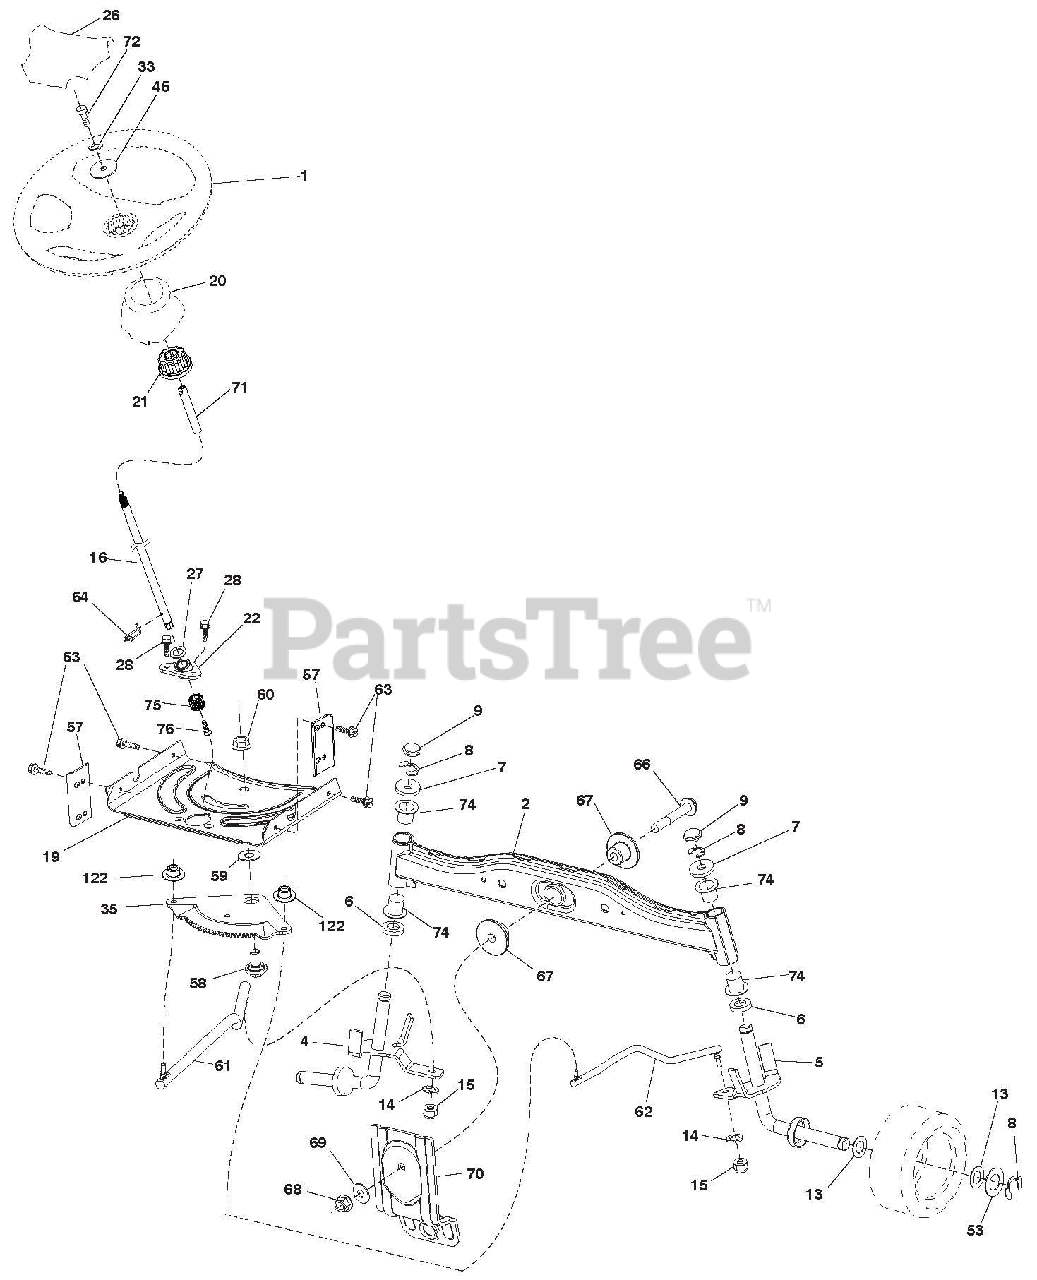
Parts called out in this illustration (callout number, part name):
1	WHEEL.STEERING.HARD RIM.BLACK
2	AXLE HALF.WELDED.
4	SPINDLE.WELDED.LH.15"TEX
5	SPINDLE.WELDED.RH.15"TEX
6	WAHSER THRUST .75 X 1.230
7	WASHER.25/32 X 1-5/8 X 16GA.
8	RING.KLIP.#T5304-75
9	CAP.SPINDLE.FR.TOP.BLK.
13	WASHER.25/32 X 1 1/4 X 16 GA.
14	Washer, Lock 3/8
15	NUT.CROWNLOCK.3/8-24
16	STEERING SHAFT
19	PLATE.STEER.DDL.NLT/NGT
20	BOOT.STEERING.LT.TEX P/L.428
21	ADAPTER.WHEEL.STRG..760
22	STEER.SUPT. LOWER
26	CAP WHEEL STEERING HRS/SRS BLK
27	Washer 21/32 x 1 x 16 Ga.
28	SCREW.HEXWSH THDR3/8-16X3/4.BL
33	Washer, Lock 5/16
35	GEAR SECTOR.PLATE.DDL.NLT/NGT
45	WASHER.11/32ID X2 3/8OD X 12GA
53	WASHER.HARDEN..793 X 1.637X060
57	BRACKET.UPSTOP.TEX
58	BOLT.SHOULDER.SECTOR.PIVOT.CFM
59	WASHER.THRUST.SECTOR.STEER.NLT
60	NUT.FLANGE LOCK.5/8-11
61	DRAGLINK.LH.BALLSTUD.DDL.
62	DRAGLINK.RH.BALLSTUD.DDL
63	SCREW.5/16-18X3/4.SMGML.TAP/BL
64	RETAINER.CLIP.SPRING.STEERING
66	BOLT.HEX.FGHD.7/16-14 X 3.SERR
67	BUSHING.PM.FRONT AXLE
68	NUT.LOCK.FLANGE.7/16-14.GR5
69	WASHER.1.5 X .505 X .118
70	BRACKET
71	Extension Steering
72	Bolt 5/16-18 x 14 w/Patch
74	BEARING COL STRNG BLK
75	PINION
122	CAP GEAR SECTOR
